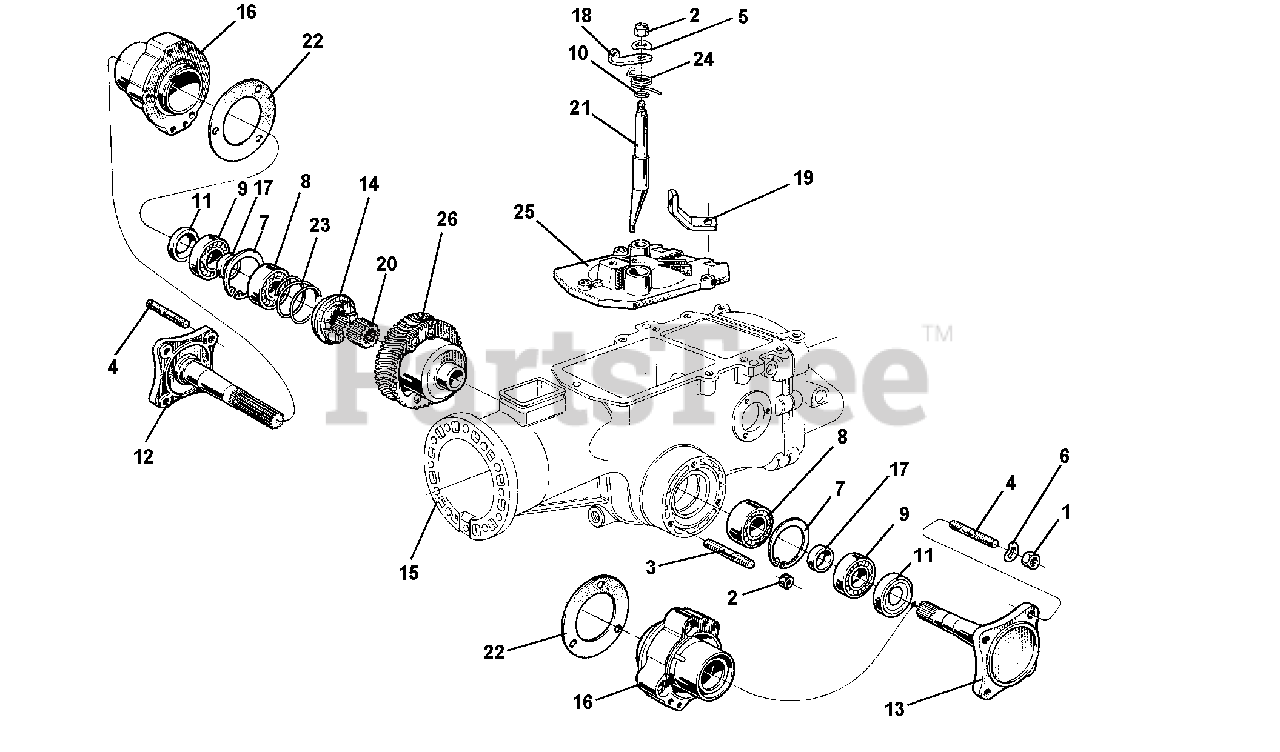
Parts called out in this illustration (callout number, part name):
2	NUT, SELF LOCKING M8
3	STUD M8 X 46 X 20 X 12
4	STUD M10 X 40 X 22 X 14
5	WASHER, FLAT 8.4
6	WASHER, LOCK 10.5
7	CIRCLIP, INTERN. D 47
8	BEARING 20 X 52 X 15 6304
9	BEARING 25 X 47 X 12 6005
10	O-RING 2056 14.00 X 1.78
11	SEAL, OIL 30 X 40 X 7 STANDARD
12	HALF AXLE RIGHT LONG
13	HALF AXLE LEFT SHORT
15	CASING 5 SPEEDS GEARBOX
16	HUB FOR HALF AXLE
17	RING FOR HALF AXLE
18	LEVER RELEASE
19	CONTRAST DIFFERENTIAL SHEATH
20	SPACER FOR DIFFERENTIAL
22	JOINT GASKET
25	COVER DIFFERENTIAL
26	DIFFERENTIAL DS Z 49
